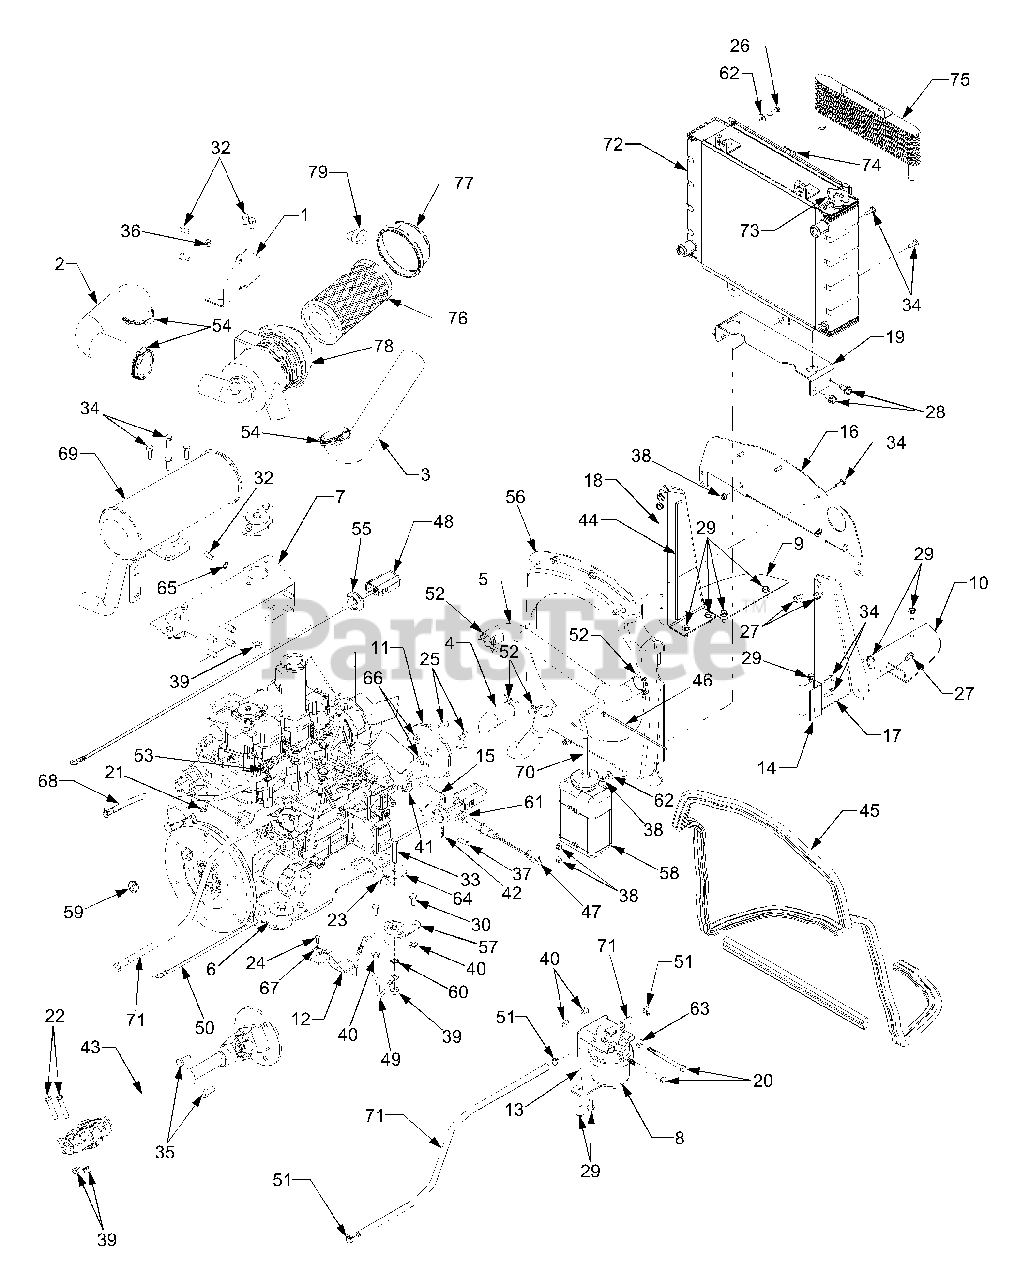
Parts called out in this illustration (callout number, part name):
1	Bracket, Air Filter Mtg.
2	Hose, Air Inlet
3	Hose, Air Filter
4	Hose, Radiator to Engine
5	Hose, Engine to Radiator
6	Bracket, Engine RH
7	Bracket, Engine LH
8	Filter Assembly, Fuel
8	Filter Element
9	Plate, Baffle RH
10	Plate, Baffle, LH
11	Plate, Engine RPM
12	Bracket, Cable Mtg.
13	Bracket, Filter Mtg.
14	Bracket, Over Flow Bottle
15	Bracket, Sensor Mtg.
16	Plate, Radiator Baffle
16	Graphic, Fan Warning
16	Graphic, Warning
17	Bracket, Radiator Mtg. RH
17	Graphic, Warning
18	Bracket, Radiator Mtg. LH
18	Graphic, Warning
19	Bracket, Radiator Mtg.
20	Screw, Hex Cap, 5/16-18 x 4.0 GR5
21	Screw, Hex Wash Hd Tapp 10-16 x .5
22	Screw, Hex Cap 3/8-16 x 1.75 GR5
23	Screw, Hex Cap, M12-1.25 x 25 GR8.8
24	Screw, Truss Mach. #10-24 x .625
25	Screw, Countersink Torx Hd M8-1.25 x 20
26	Screw, Hex Cap 1/4-20 x 1.0 GR5
27	Screw, Hex Wash Hd Tapp 5/16-18 x .5
28	Screw, Hex Wash Hd Tapp 3/8-16 x .75
29	Screw, Hex Wash Hd Tapp 5/16-18 x .75
30	Screw, Hex Cap 5/16-18 x .75 GR5
31	Screw, Hex Cap 1/4-20 x .75 GR5
32	Screw, Hex Cap, M8-1.25 x 16
33	Screw, Hex Cap
34	Screw, Hex Cap, M8-1.25 x 25 GR8.8
35	Screw, Hex Cap, M10-1.5 x 25 GR5
36	Screw, Hex Cap, M6-1.0 x 10 GR8.8
37	Pin, Clevis, .312 x 1.0
38	Nut, Hex Insert Lock, 1/4-20
39	Nut, Hex Flange Lock, 3/8-16
40	Nut, Hex Flange Lock, 5/16-18
41	Nut, Jam, 5/8-18 GR5
42	Pin, Internal Cotter
43	Shaft, Drive
44	Tape, Foam, .625 wide 42in.
45	Seal, Heat Baffle 104in
46	Tie, Cable
47	Sensor, RPM
48	Wire, Battery Pos.
49	Wire, Ground
50	Wire, Battery Neg.
51	Clamp, Hose
52	Clamp, Hose
53	Clamp, Hose
54	Clamp, Adjustable Hose
55	Grommet, Hose Guard
56	Shroud, Fan
57	Mount, Compression Engine
58	Container, Over Flow
59	Grommet, Rubber
60	Washer, External Lock, 3/8
61	Washer, Lock, 5/8
62	Washer, Flat, .28 x .74 x .063
63	Washer, Flat, .344 x .688 x .065
64	Washer, Flat, .38 x 2.0 x .12
65	Washer, External Lock, 5/16
66	Washer, Flat, .344 x .75 x .12
67	Clamp, Casing
68	Hose, Fuel Line 63in.
69	Muffler, Engine
70	Hose, Over Flow
71	Fuel Line, 5/16 ID 83in.
72	Grommet, Rubber Mtg.
73	Cap, Radiator, 13psi
74	Screen, Debris
75	Cooler, Oil
76	Element, Air Cleaner
77	Cap, Air Cleaner
78	Canister, Air Cleaner
79	Nozzle, Air Cleaner
